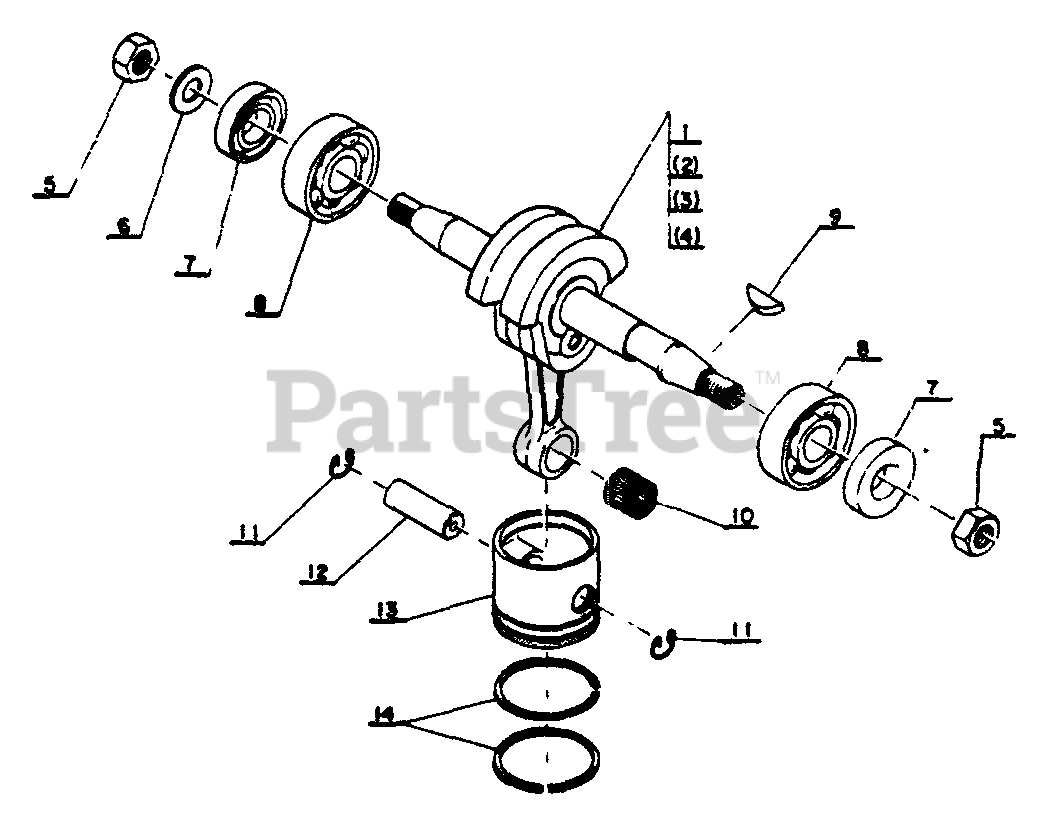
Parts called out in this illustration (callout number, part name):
1	CRANKSHAFT ASSY
6	WASHER - 8
7	SEAL, OIL
8	BEARING, BALL
10	BEARING, NEEDLE
11	RING, RETAINING
12	PIN, PISTON
14	RING, PISTON
